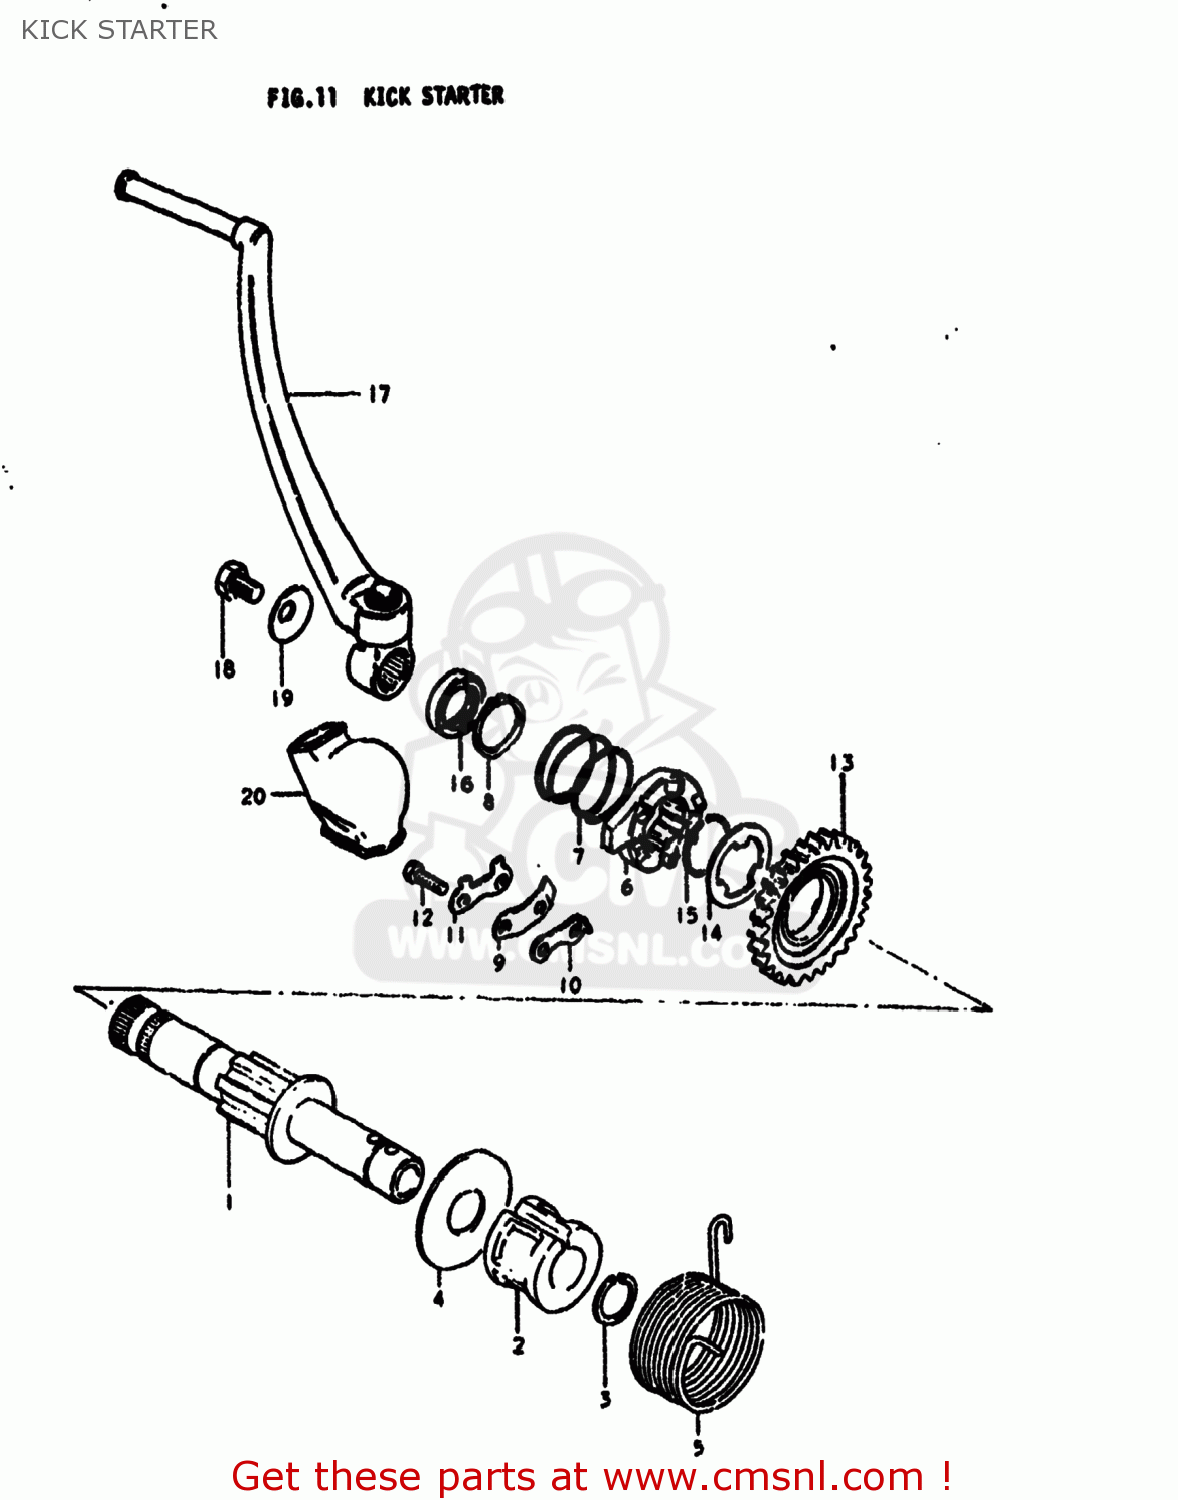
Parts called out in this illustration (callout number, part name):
1	SHAFT,KICK STARTER
2	GUIDE,KICK SHAFT SPRING
3	CIRCLIP
4	WASHER
5	SPRING
6	STARTER,KICK
7	SPRING
8	CIRCLIP
9	GUIDE,KICK STARTER
10	STOPPER,KICK STARTER
11	WASHER
12	BOLT, UPPER
13	GEAR,KICK STARTER DRIVE
14	WASHER,LOCK
15	RING,SNAP
16	SEAL,OIL(20X27X5)
17	LEVER ASSEMBLY,KICK STARTER
18	BOLT
19	WASHER(8.2X23X3.2)
20	COVER,KICK LEVER JOINT
